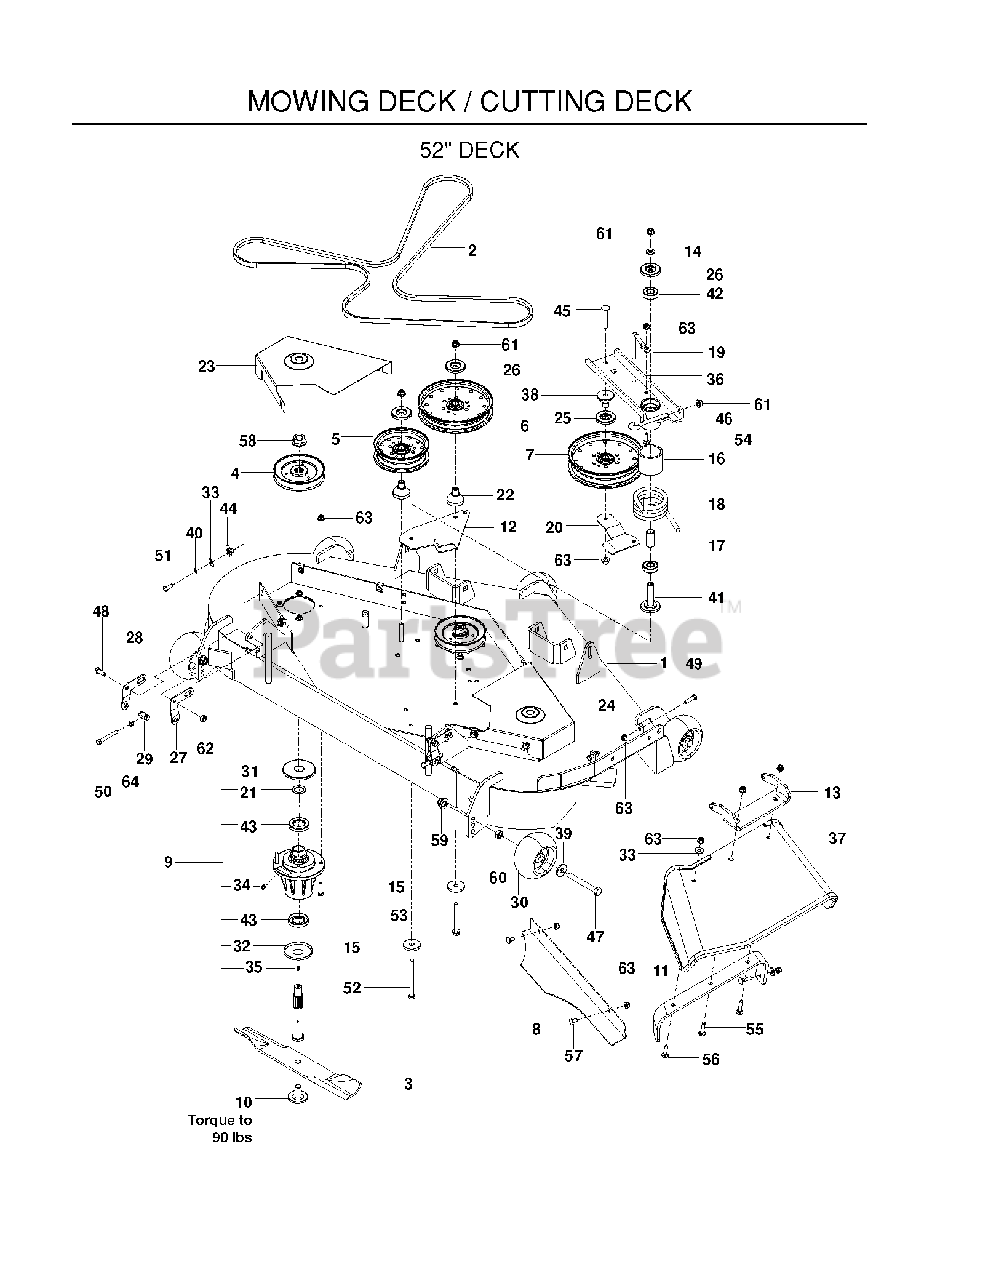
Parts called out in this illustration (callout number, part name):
4	PULLEY 52
5	IDLER PULLEY
6	PULLEY - 7" NARROW
7	PULLEY - IDLER 7"
8	CONFINEMENT PLATE, 52"
10	BLADE BOLT/WASHER
11	BRKT, REINF - CHUTE 52/61"
13	PIVOT BRACKET - CHUTE
14	WASHER, 3/8 THICK
15	SPINDLE WASHER
16	SPACER, IDLER PIVOT
17	SPACER, IDLER BEARINGS
18	SPRING, TORSION, IDLER
19	BELT KEEPER
20	BELT GUIDE, BLK
21	MACHINE BUSHING
23	SHIELD, BELT, 52 LT, BLUE
24	SHIELD, BELT, 52 RT, BLUE
25	SHIELD, DUST
26	DUST SHIELD
27	PITCH, ADJUST, LT
28	PITCH, ADJUST, RT
29	TRUNION, PITCH
31	TOP DUST CAP
32	BOTTOM DUST CAP
33	WASHER 5/16 FLAT
34	PLUG-VENTED
37	CHUTE, RUBBER DISCHARGE 52/61"
38	BEARING, IDLER ARM
39	WASH USS FLAT 1/2
40	WASH 5/16 DISC SPRING ZD
41	BEARING, IDLER PIVOT
42	BEARING, BALL
43	SHAFT SEAL
44	U-CLIP 5/16-18 NUT RETAINER
45	CARRIAGE BOLT 3/8-16 X
46	EYE BOLT, 3/8 X 4"
47	HCS 1/2-13 X 4 GR 5 ZD
48	HCS 3/8C X 1
49	HCS 5/16C X 1 1/4
50	HCS 5/16-18 X 2 1/2 TPBLT
51	HCS 5/16C X 3/4
52	HCS 3/8-16 X 4-1/2 GR 8 ZD
54	RHSSNB 5/16C X 1.0
55	RHSNB 5/16-18 X 1-1/2 GR 5 ZD
56	BOLT, CARRIAGE 5/16X1-1/4
57	CARRIAGE BOLT 5/16C X 5/8"
58	NUT FLANGE 3/4-16
59	NUT, 1/2-13 HEX FLG NYLOC ZD
60	NUT 1/2 HEX JAM
61	NUT 3/8-16 HEX FLG NYLOC ZD
62	NUT 3/8-16 NYLOC
63	5/16-18 NYLOC FLANGE NUT
64	NUT 5/16C HEX
